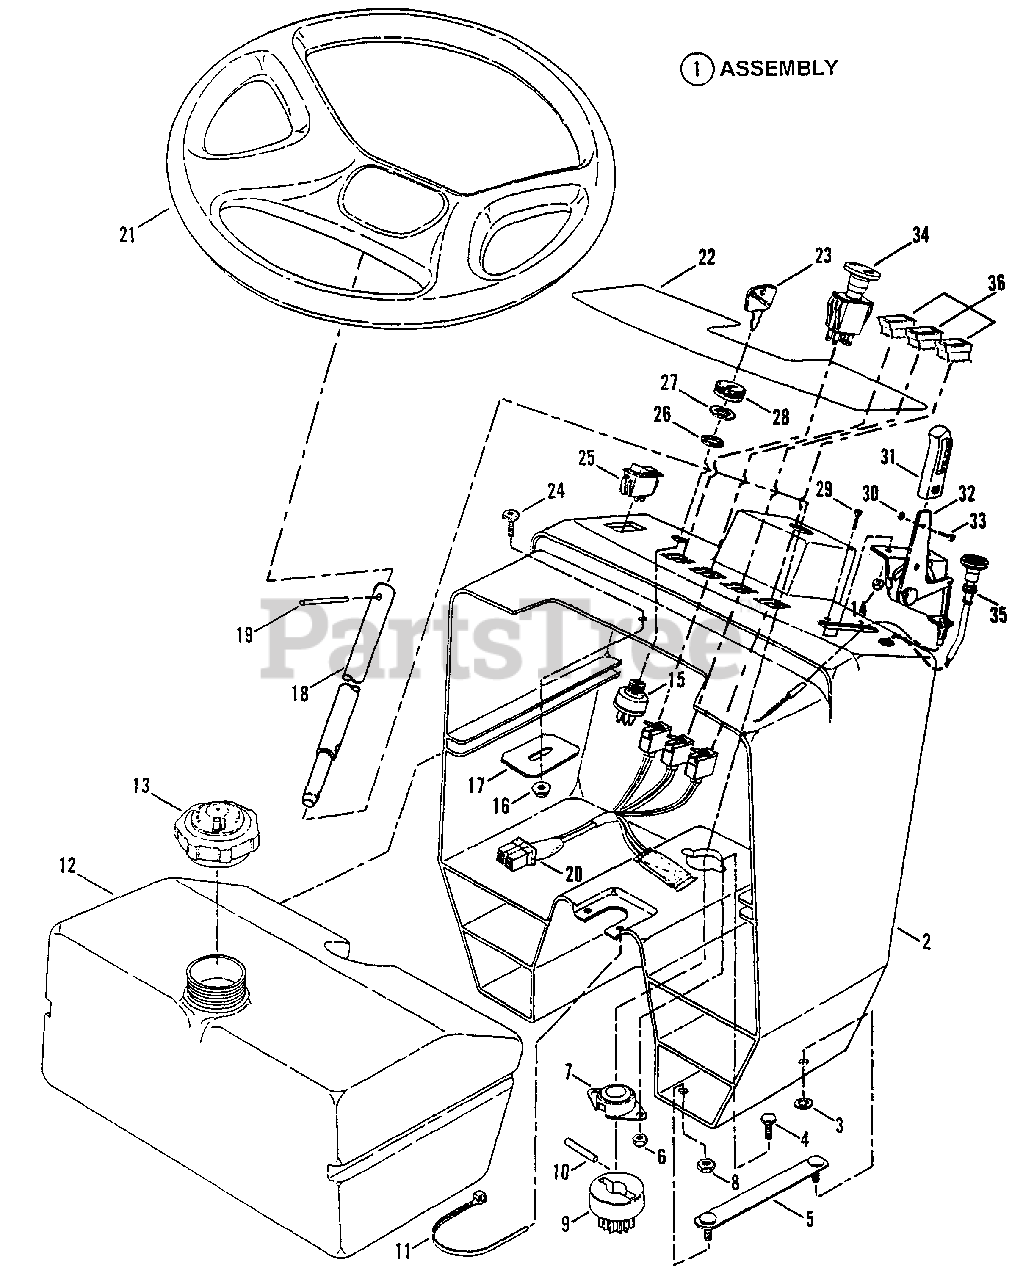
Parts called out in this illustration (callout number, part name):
1	ASSEMBLY, Console
2	CONSOLE
3	RETAINER, 5/16 Bolt
4	SCREW, 1/4-20 x 3/4 Hex Head Cap, Grade 5
5	ASSEMBLY, Strap-Clinch Stud
6	NUT, 1/4-20 Hex Nyloc
7	ASSEMBLY, Flange Bearing
8	NUT, 5/16-18 Hex Center Lock, Grade B or 5
9	GEAR, Pinion, Steering Shaft
10	PIN, Dowel, 1/4 x 1-1/4"
11	TIE, Wire
12	ASSEMBLY, Fuel Tank
13	CAP, Fuel Tank
14	NUT, #10-24 Hex Nyloc
15	KEYSWITCH
16	NUT, 5/16-18 Hex Flange Lock
17	BRACKET, Hood Latch Catch
18	SHAFT, Steering
19	ROLL-PIN, 1/4 x 2-1/4
20	LIGHTS, Indicator
21	STEERING WHEEL
22	DECAL, Console
23	KEY, Switch (With Cover)
24	SCREW, 5/16-18 x 5/8" Truss Head, Torx
25	SWITCH, Lights
27	NUT, 5/8-32 Hex
28	BEZEL
29	SCREW, #10-24 x 5/8" Machine
30	NUT, #8-32 Hex, Grade 2-B
31	HANDLE, Throttle Control
32	CONTROL, Throttle 44.6" Long
32	CONTROL, Throttle 26.25" Long
33	SCREW, #3-32 x 3/8 Cross-Recessed, Fillester Head, Grade 2
34	SWITCH, PTO
35	CABLE, Choke 29.1" Long
36	LENS, Indicator Light
